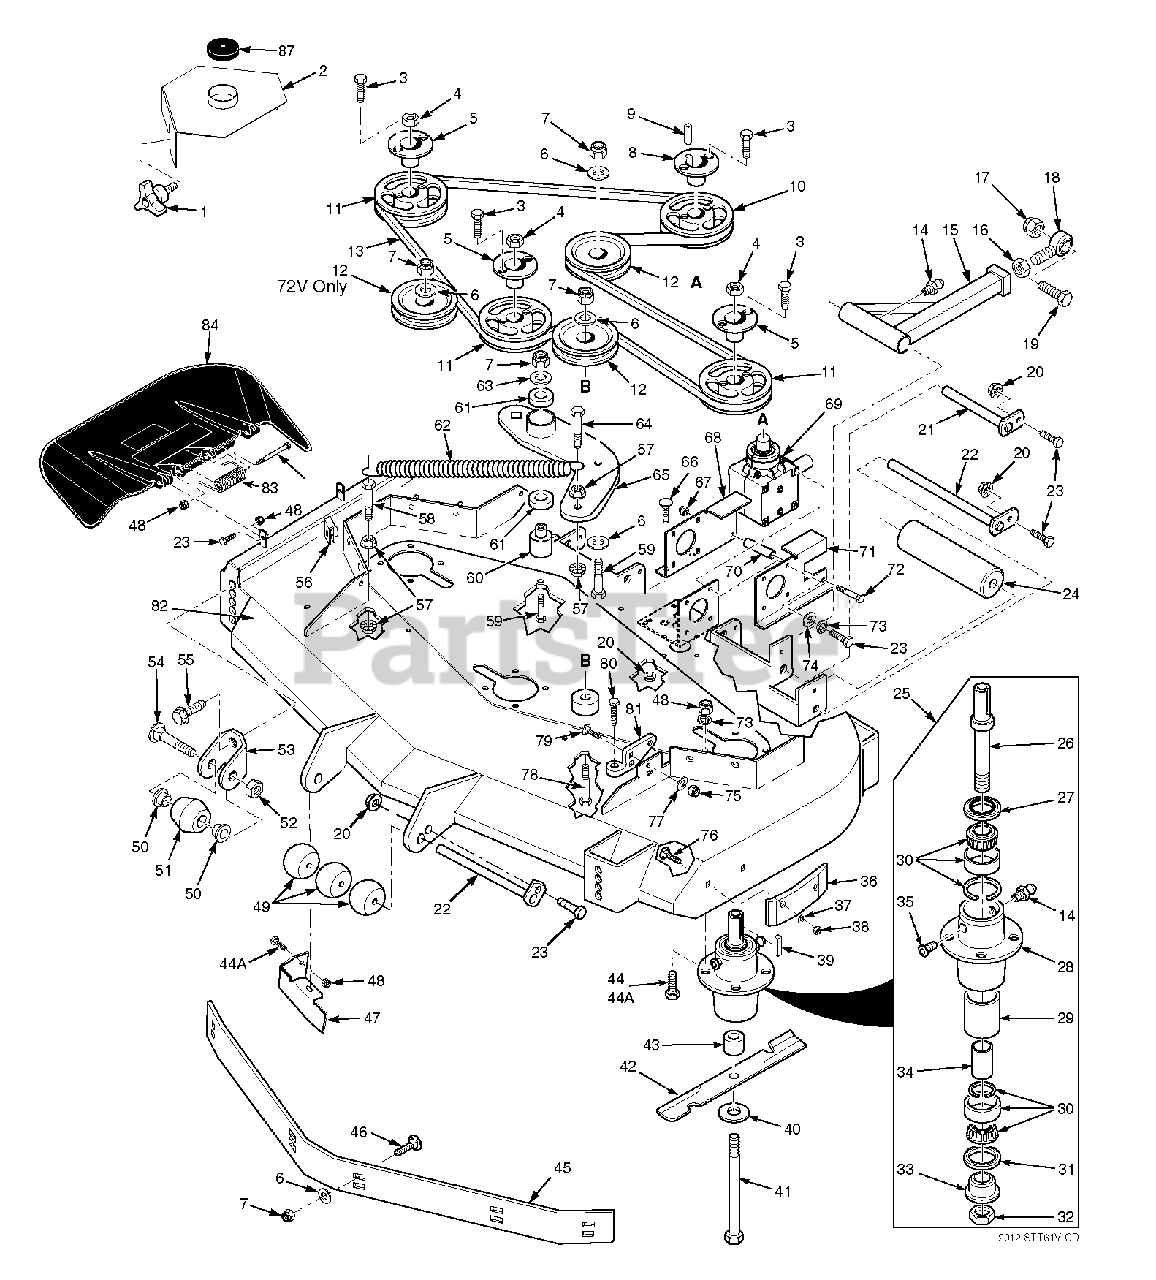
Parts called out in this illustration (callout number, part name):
1	Wing Nut, 3/8-16
2	Belt Cover Assembly
2	Belt Cover Assy., RH
2	Belt Cover Assy., LH
3	Bolt, Hex Head 1/4-20 x 1" Grd 8
4	Nut, 5/8-11 UNC
5	Tapered Hub, 1-1/8" Bore
6	Flatwasher, 3/8"
7	Nut, Hex Elastic Stop 3/8-16
8	Tapered Hub, 1" Bore
9	Key, 1/4 x 1/4 x 1-1/4"
10	Pulley, 6.75 O.D.
10	Pulley, 6.35 O.D.
11	Pulley, 6.35 O.D.
11	Pulley, 6.95 O.D.
12	Pulley, Idler
13	Belt, Cutter Deck Drive
14	Grease Fitting
15	Pusharm
16	Nut, Hex Head 5/8-18 UNF
17	Nut, Hex Elastic Stop 5/8-11
18	Rod End, 5/8" Male RH Thread
19	Bolt, Hex Head 5/8-11 x 4-1/2"
20	Nut, Hex Serrated Flange 5/16-18
21	Push Arm Shaft
22	Roller Shaft
23	Bolt, Hex Head 5/16-18 x 1-3/4"
24	Wheel, Anti-Scalp
25	Spindle Assembly
26	Spindle Shaft
27	Seal, Top
28	Spindle Housing
29	Spacer, Outside
30	Bearing Assembly
31	Seal, Bottom
32	Nut, Special 1-1/16-18
33	Spindle Bushing, Bottom
34	Spacer, Inside
35	Relief Fitting, Tapered Spindle
36	Wear Pad
37	Flatwasher, 5/16"
38	Nut, Center Lock 5/16-18
39	Key, 1/4 x 1/4 x 2"
40	Flatwasher, 5/8" Hardened
41	Bolt, Hex Head 5/8-11 x 9-1/2"
42	Cutter Blade, 21"
42	Cutter Blade, 24.5"
43	Spacer, Spindle Bottom
44	Bolt, Hex Head 5/16-18 x 1-3/4"
45	Baffle, Custom Cut 61V
45	Baffle, Custom Cut 72V
46	Bolt, Carriage 3/8-16 x 1"
47	Discharge Baffle
48	Nut, Hex Elastic Stop 5/16-18 Grd 8
49	Wheel, Anti-Scalp
50	Bushing, .376 I.D. Oilite
51	Anti-Scalp Wheel
52	Locknut, 3/8-16 Center Lock
53	Anti-Scalp Wheel Bracket
54	Bolt, Carriage 3/8-16 x 4"
55	Bolt, Hex Serrated Flange 3/8-16 x 1"
56	U-Nut, 3/8-16
57	Nut, Hex Serrated Flange 3/8-16
58	Bolt, Hex Head 3/8-16 x 1-1/2"
59	Bolt, Hex Head 3/8-16 x 3"
60	Pivot, Idler - Short
61	Bearings, Ball
62	Spring, Cutter Deck
63	Flatwasher,3/8-.39 x .938 x .105 HD
64	Bolt, Hex Head 3/8-16 x 1-1/2" Grd 8
65	Idler Arm, Cutter Deck
66	Bolt, Carriage 5/16-18 x 3/4"
67	Nut, Elastic Stop 5/16-18
68	Mounting Plate, RH Gearbox
69	Gearbox Assembly, Deck Drive
70	Spacer, Gearbox Mount
71	Mounting Plate, LH Gearbox
72	Bolt, Hex Head 5/16-18 x 4-3/4"
73	Lockwasher, 5/16"
74	Flatwasher, 5/16"
75	Nut, Elastic Stop 7/16-14
76	Bolt, Carraige 5/16-18 x 3/4"
77	Flatwasher, 7/16-.500 x 1.25 x .083
78	Bolt, Hex Head 3/8-16 x 3-1/4"
79	Bolt, Carriage 7/16-14 x 1-1/4"
80	Bolt, Deck Adjust
81	Lever Assy, Deck Level
82	Cutter Deck
83	Spring, Discharge Chute
84	Discharge Chute Assembly
85	Bolt, Hex Head 5/16-18 x 4-1/2"
86	Bolt, Carriage 5/16-18 x 1-1/4"
87	Cap, Spindle
